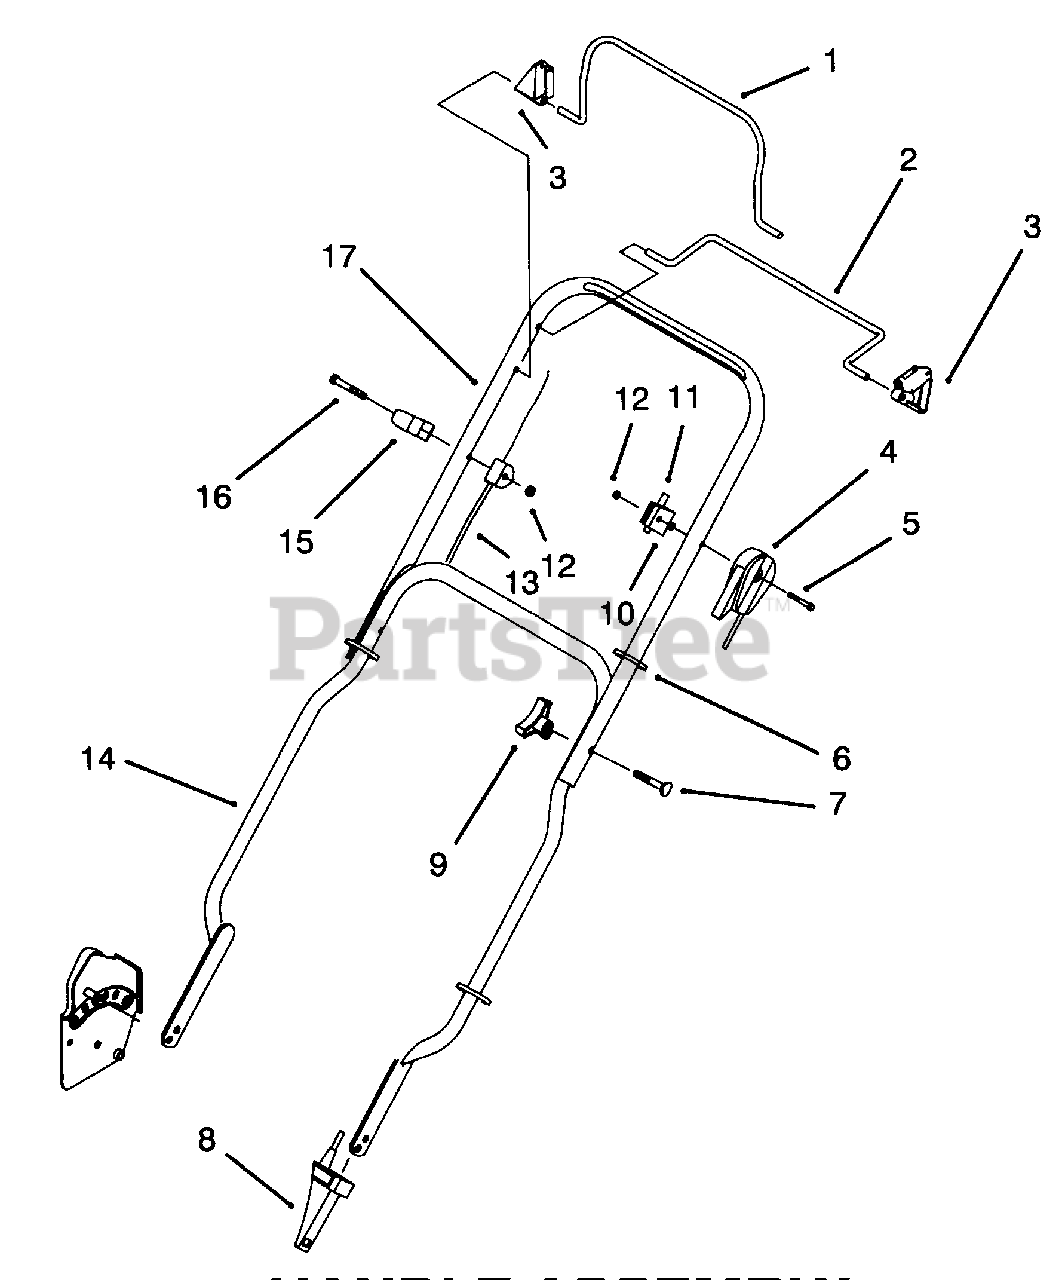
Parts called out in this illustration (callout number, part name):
1	Bail-Flywheel Brake
2	Bail-SP Control
3	Stop-Pivot
4	Cable-Throttle
5	Screw-Hex Hd. Cap
6	Strap-Tie
7	Screw-Handle
8	Anchor-Cable SP Lower
9	Knob
10	Anchor-Cable SP Upper
11	Cable-Traction
12	Nut-Lock
13	Cable-Flywheel Brake
14	Handle-Lower
15	Guide-Rope
16	Screw-Hex Hd Cap
17	Handle-Upper
